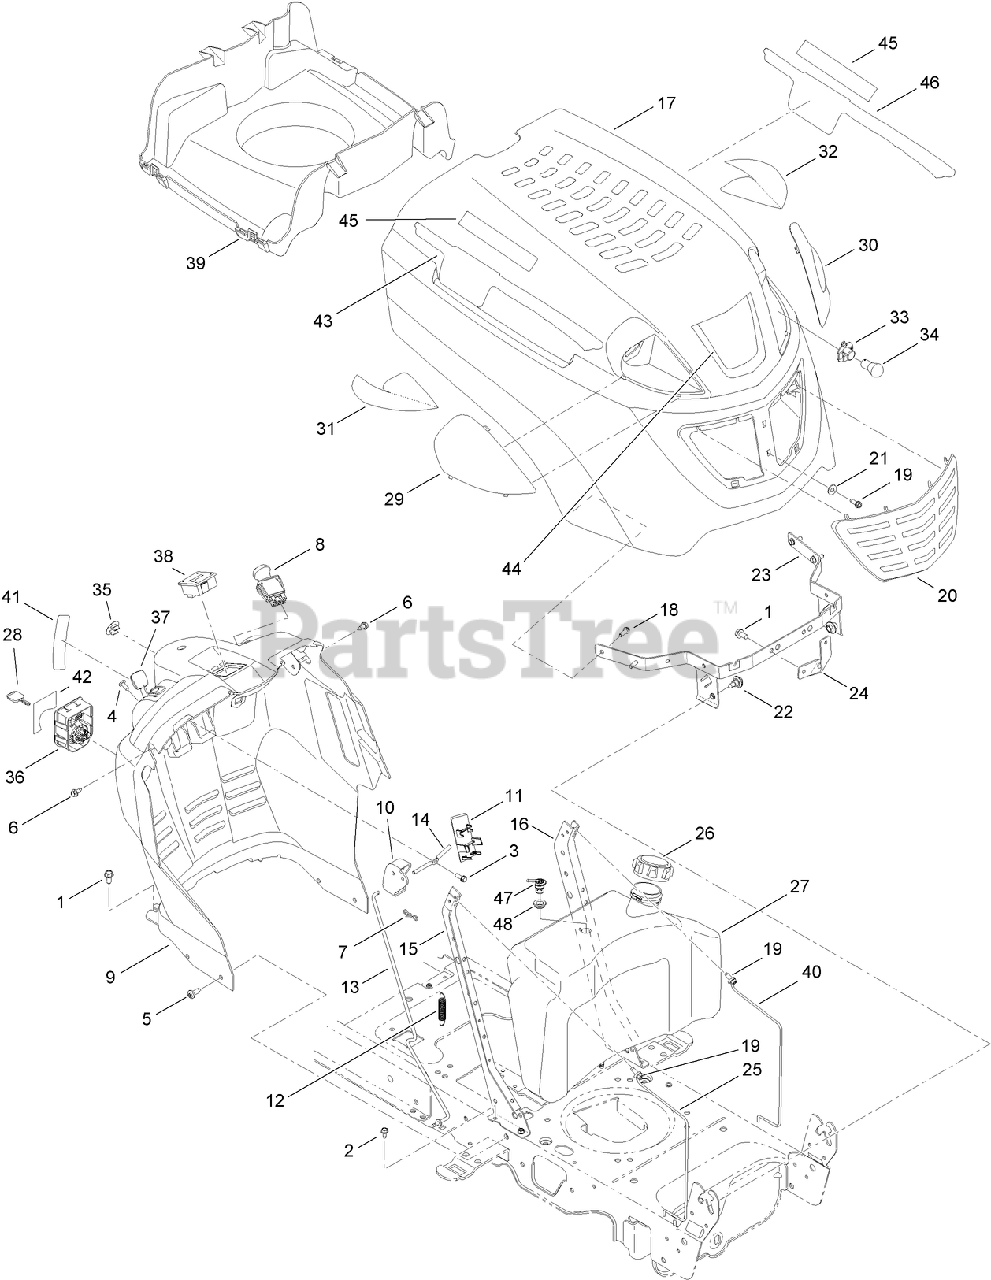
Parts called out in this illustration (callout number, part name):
1	SCREW-TAP
2	SCREW-HWHTF
3	SCREW-TAP
4	SCREW-TAP
5	SCREW-TAP
6	SCREW-HWH
7	PIN-COTTER
8	SWITCH-ELECTRIC, PTO
9	DASH-ELECTRIC, PTO
10	LEVER-DASH
11	COVER-CRUISE
12	SPRING-EXTENSION
13	ROD-LATCH
14	ROD-LEVER, BENT
15	SUPPORT-DASH, PLATE (RH)
16	SUPPORT-DASH, PLATE (LH)
19	SCREW-TAP
21	WASHER-FLAT
22	BOLT-SHOULDER, TAP
23	BRACKET-PIVOT
24	BRACKET-SUPPORT, HOOD
25	ROD-SUPPORT
26	CAP-FUEL
27	TANK-FUEL
28	KEY-IGNITION
29	LENS-RH
30	LENS-LH
31	REFLECTOR-RH
32	REFLECTOR-LH
33	SOCKET-HEADLIGHT
34	LAMP-12V, MINIATURE
35	PLUG-CHOKE
36	MODULE-SWITCH, IGNITION
37	CABLE-THROTTLE
38	METER-HOUR
39	PLENUM-HOOD
40	ROD-SUPPORT, LH TANK
41	DECAL-THROTTLE
43	DECAL-HOOD, RIGHT SIDE
44	DECAL-HOOD
45	DECAL-SIDE PANEL
46	DECAL-HOOD, LEFT SIDE
47	VALVE, ROLLOVER GROMMET
48	GROMMET, RUBBER, 23.0 ID
